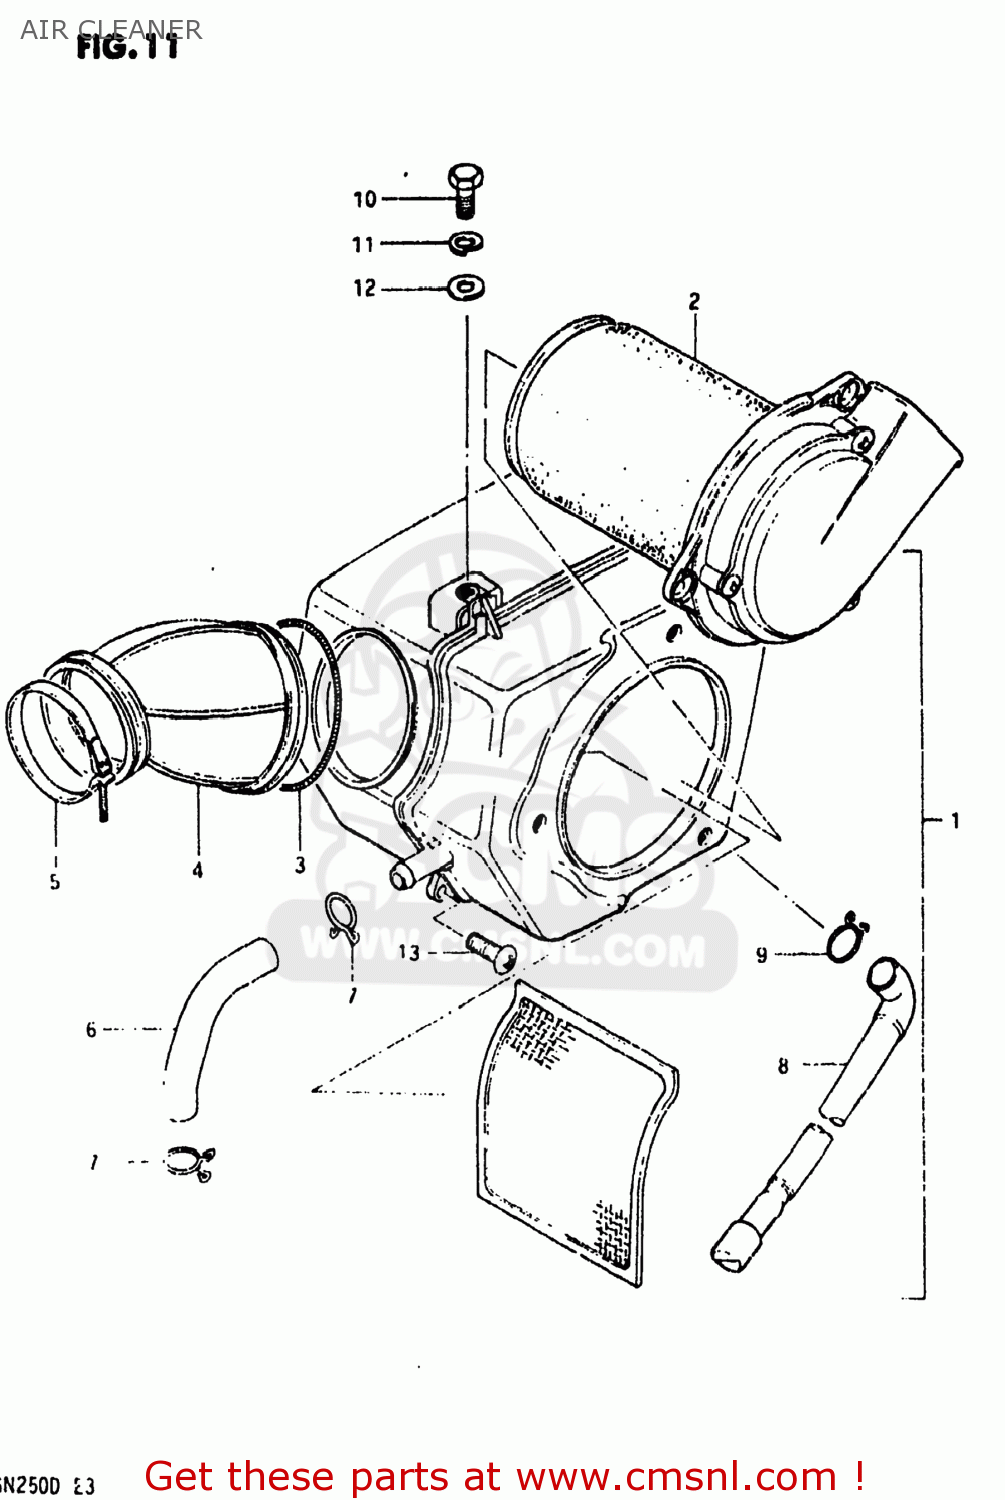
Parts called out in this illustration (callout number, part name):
1	CLEANER ASSEMBLY,AIR
2	FILTER,AIR CLEANER
3	CLAMP,AIR CLEANER SIDE
4	TUBE,OUTLET
5	CLAMP
6	TUBE,BREATHER
7	CLIP,BREATHER TUBE
8	DRAIN TUBE
9	CLIP
10	BOLT, UPPER
11	LOCK WASHER
12	WASHER
13	SCREW
